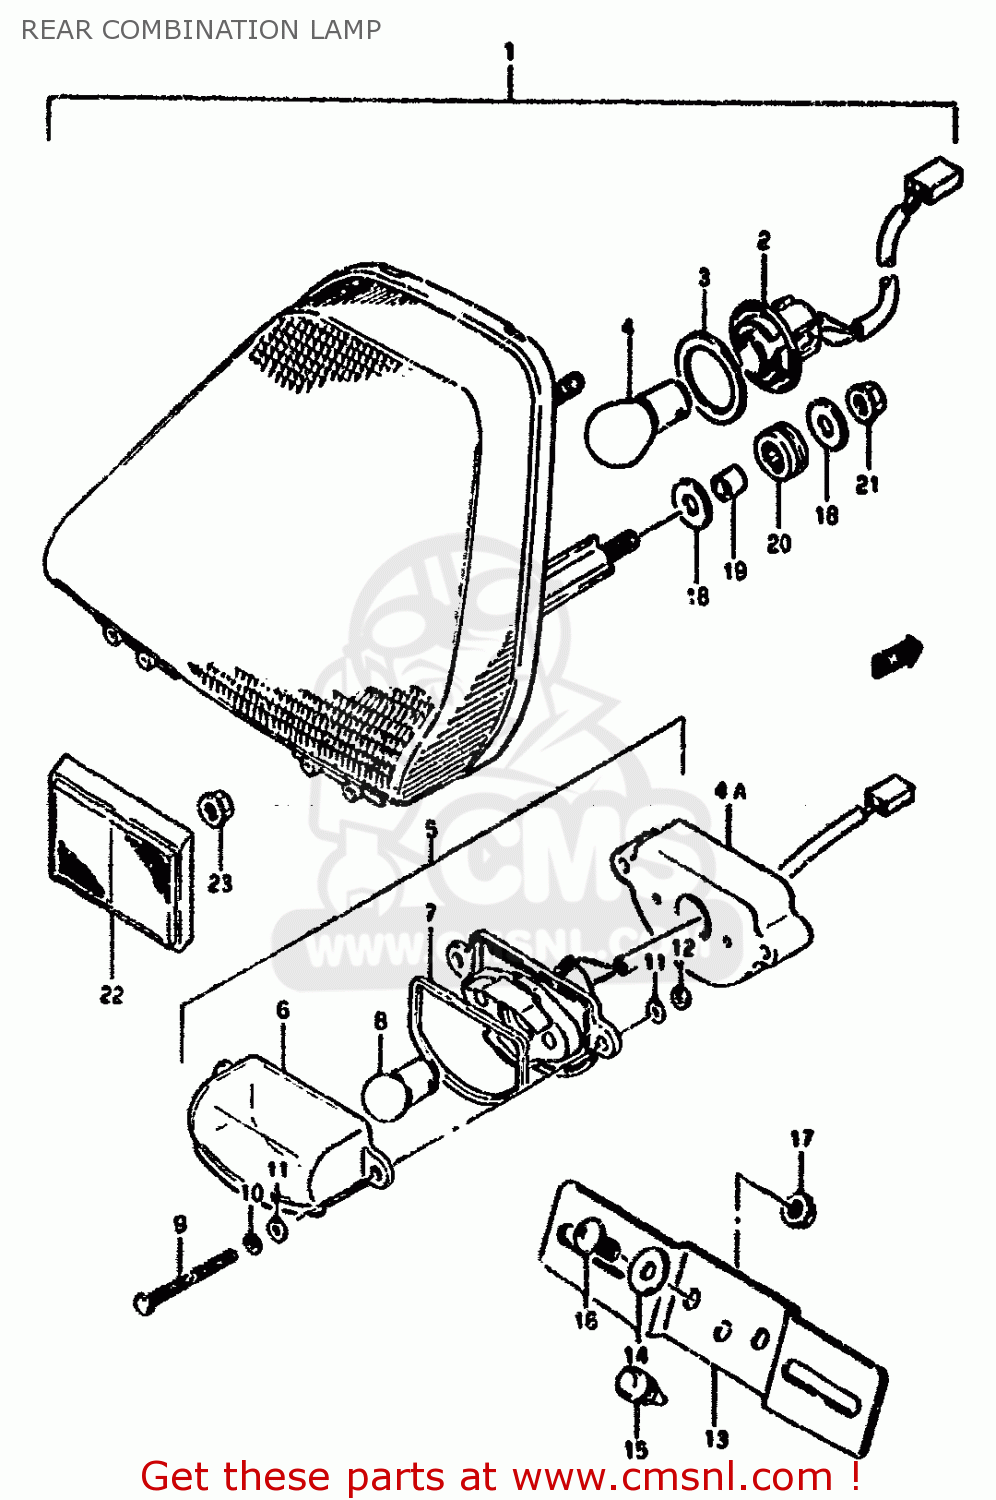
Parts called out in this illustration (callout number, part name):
1	LAMP ASSY,RR C
2	SOCKET
3	CUSHION,RUBBER
4	BULB(12V21/5W)
4A	SPACER,LICENSE LAMP
5	LAMP ASSY,LICENSE
6	LENS,LICENSE LAMP
7	GASKET,LICESE LAMP (NAS)
8	BULB
9	BOLT
10	WASHER,LOCK 4M
11	WASHER 4MM
12	NUT 4MM
13	PLATE,RR LICENSE
14	WASHER(6.5X20X1.6)
15	CUSHION
16	SCREW
17	NUT
18	WASHER (6.5X20X1)
19	SPACER (6.1X9X9)
20	CUSHION
21	NUT
22	REAR ASSEMBLY,REAR
23	NUT
